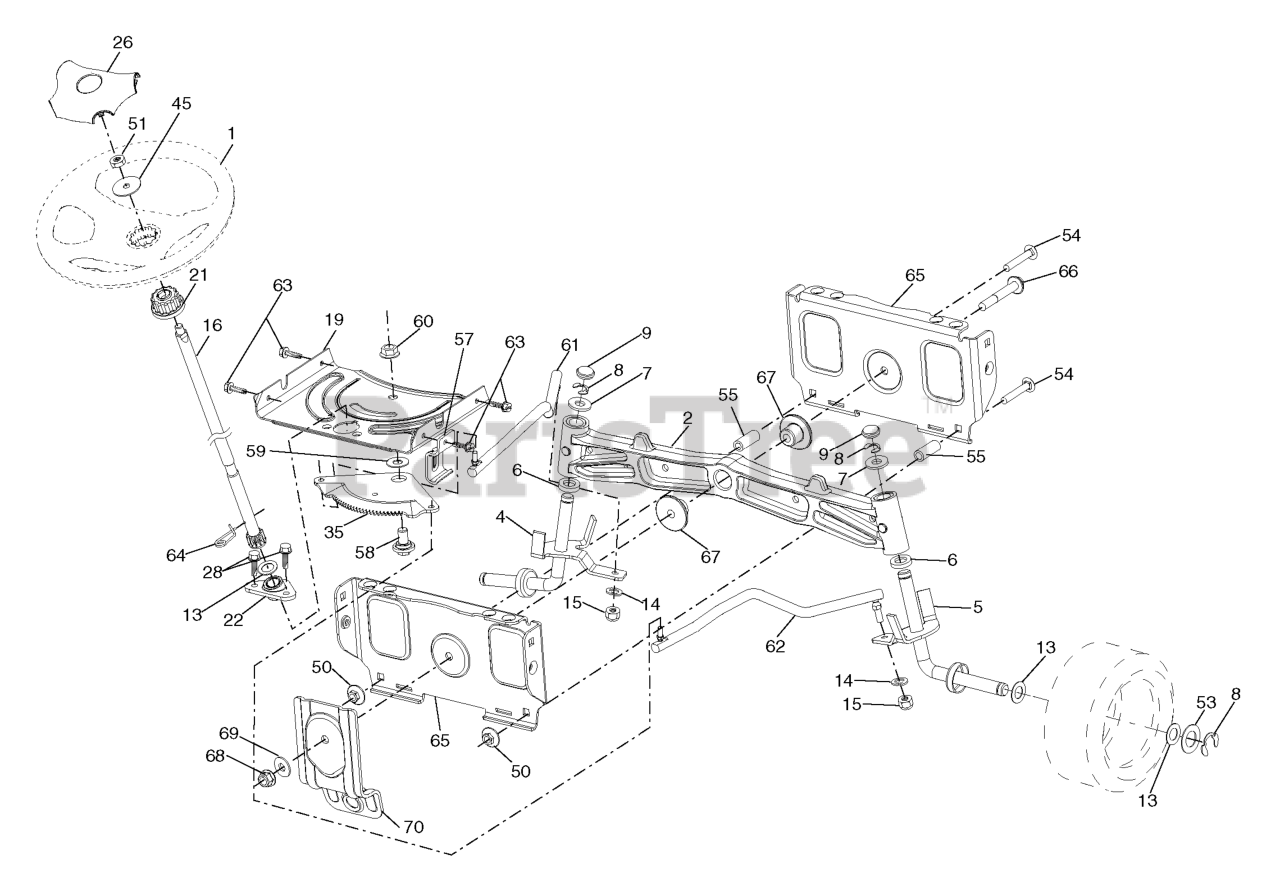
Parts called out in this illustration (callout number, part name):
1	WHEEL.STEERING.LEGEND2.GRY
2	AXLE.CAST.IRON
4	SPINDLE.WELDED.LH.15"TEX
5	SPINDLE.WELDED.RH.15"T
6	THRUST WASHER
9	CAP.SPINDLE.BLACK
14	WASHER, LOCK 3/8
15	NUT CROWNLOCK 3/8-24
16	SHAFT.STEER.STEALTH.DD
19	PLATE.STEER.DDL.NLT/NG
21	ADAPTER, WHEEL STNG..
22	BUSHING.ASM.STEERING.A
26	INSERT.CAP.STRG.WH.GRAY
28	SCREW, 3/8-16X3/4
35	GEAR.SECTOR.PLATE.DDL.
45	WASHER 9/16"ID, 2 3/8"OD
50	NUT LOCK FLG 3/8-16 UNC
51	NUT.HEX.1/2-20
53	WASHER.HARDENED
55	SPACER.BRACE.AXLE (2 2)
57	BRKT.UPSTOP.GT/LT.TEX
58	BOLT.SHOULDER.SECTOR.P
59	WASHER.THURST.SECTOR.S
60	NUT FLANGE LOCK 5/8-11
61	DRAGLINK.LH.BALLSTUD.D
62	DRAGLINK.RH.BALLSTUD.D
63	SCREW
64	RETAINER.CLIP.SPRING.S
65	BRACE.AXLE.FRONT.NLT/N
66	BOLT HEX FGHD 7/16-14 X 3 SERR
67	BUSHING.PM.FRONT AXLE
68	NUT.LOCK.FLANGE.7/16
69	WASHER.1.5X.505X.118
70	BRKT.DECK.SUSPENSION.F
